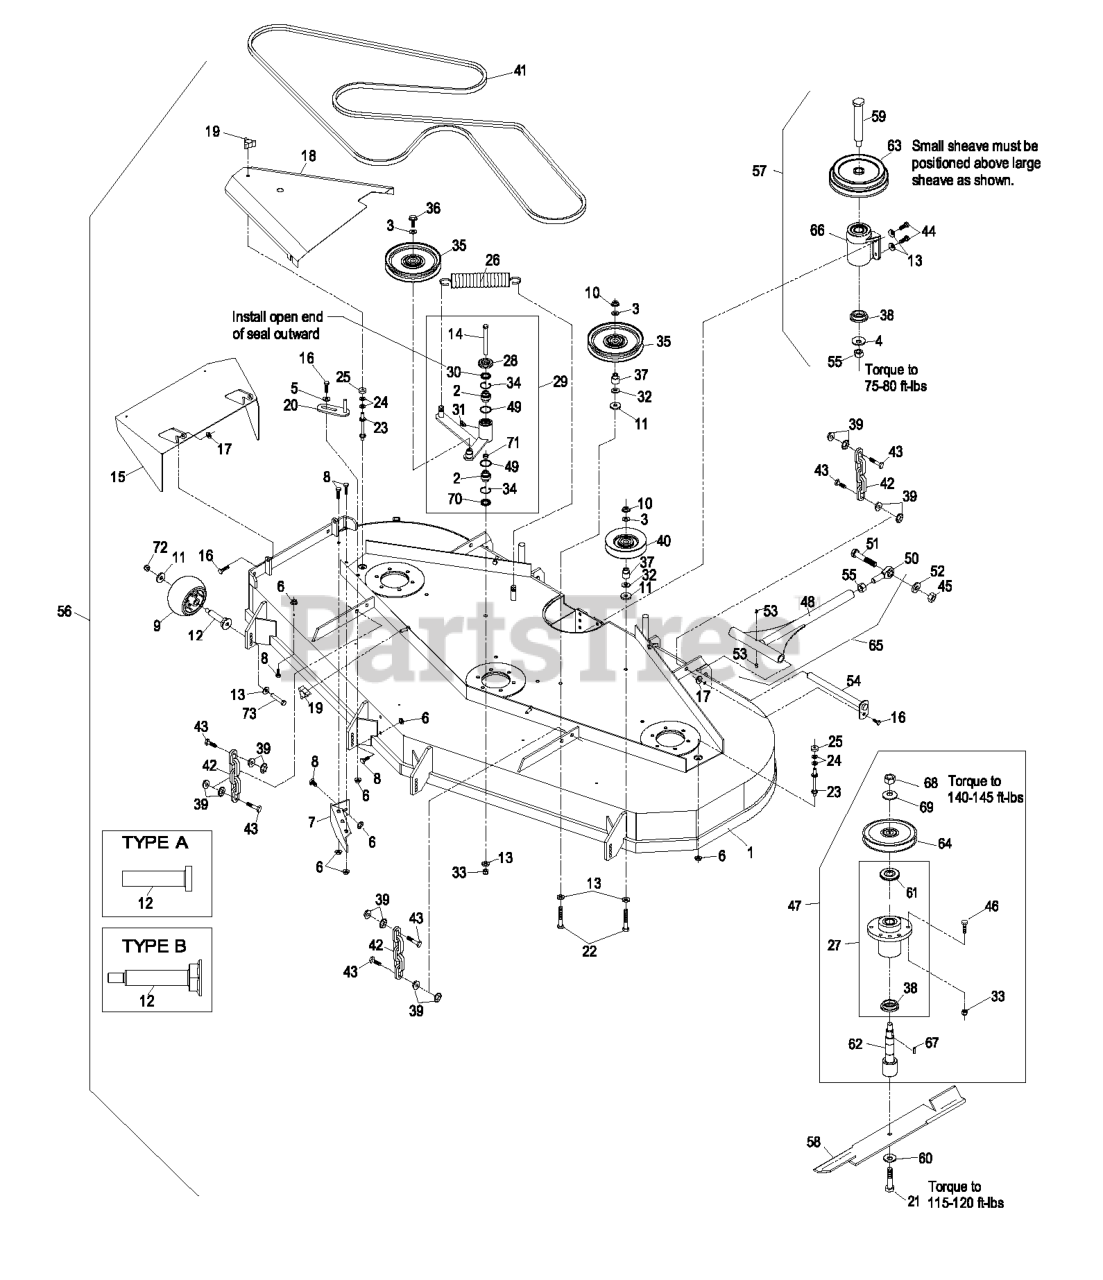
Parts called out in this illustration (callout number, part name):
1	ASM,DECK W/DECALS LZ/XP72
2	BEARING-SPHERICAL
3	WASHER-FLAT
4	WASHER-SPRING
5	WASHER-SPRING
7	WLD,BAFFLE DISCHARGE
8	SCREW-HH
9	ROLLER-SCALP, ANTI
10	NUT-HHF, WHIZ
12	BUSHING-ROLLER
13	WASHER-BELLEVILLE
14	SCREW-HH
15	WLD,CHUTE 72
16	SCREW-HH
17	NUT-LOCK, NI
18	SHIELD,BELT RH
19	KNOB-3 PRONG
20	GUIDE-BELT
21	SCREW-CAP
22	SCREW-HH
23	STUD-SHIELD, BELT (SHORT)
24	WASHER-FLAT
27	KIT, CUTTER HOUSING
28	GUARD-TOP
29	KIT,DECK IDLER LZ/XP
30	SEAL-LIP, SINGLE
31	FITTING-GREASE, 90 DEG
32	WASHER-FLAT
33	NUT-LOCK, NI
34	RING-SNAP
36	SCREW-HHF
37	BUSHING-IDLER
38	SPACER-GUARD, BOTTOM
40	PULLEY-IDLER
41	BELT-V
42	CHAIN-LIFT, DECK
43	SCREW-HH
44	SCREW-HH
45	NUT-HEX
46	SCREW-HH
47	ASM, CUTTER HSG COPL 72
50	BALLJOINT-SPHERICAL
51	SCREW-HH
52	WASHER-LOCK
53	FITTING-GREASE
54	PIN-STRUT
55	NUT-HEX
56	Asm, Deck Complete
57	KIT,JACKSHAFT 60/72-3750
59	JACKSHAFT
60	WASHER-BLADE BOLT, HEAVY
61	GUARD-BEARING, TOP
62	SPINDLE,SHORT
63	SHEAVE, JACKSHAFT DOUBLE
64	SHEAVE,BLADE DRIVE 7.5
65	STRUT WLDMT S/A
68	NUT-HH
70	SEAL-LIP, DOUBLE
72	NUT-HHF, WHIZ
73	SCREW-HH
